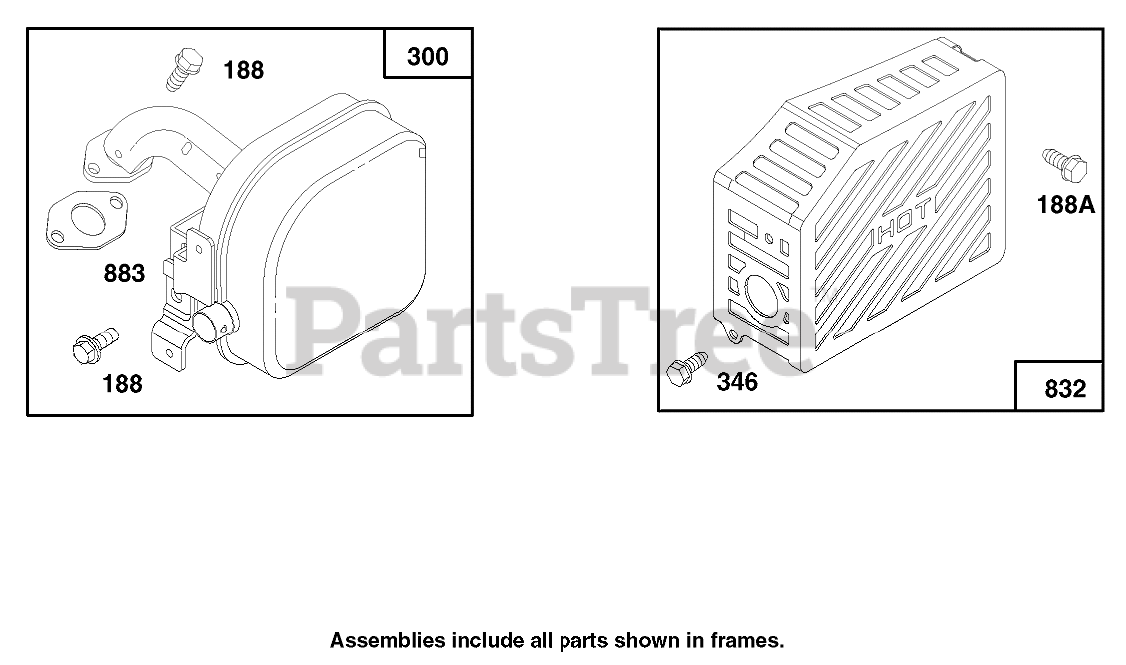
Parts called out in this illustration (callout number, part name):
188	SCREW - HEX HEAD
188A	SCREW - SEM
300	MUFFLER - EXHAUST
346	SCREW - SELF-TAPPING
832	Guard-Muffler
883	EXHAUST GASKET
